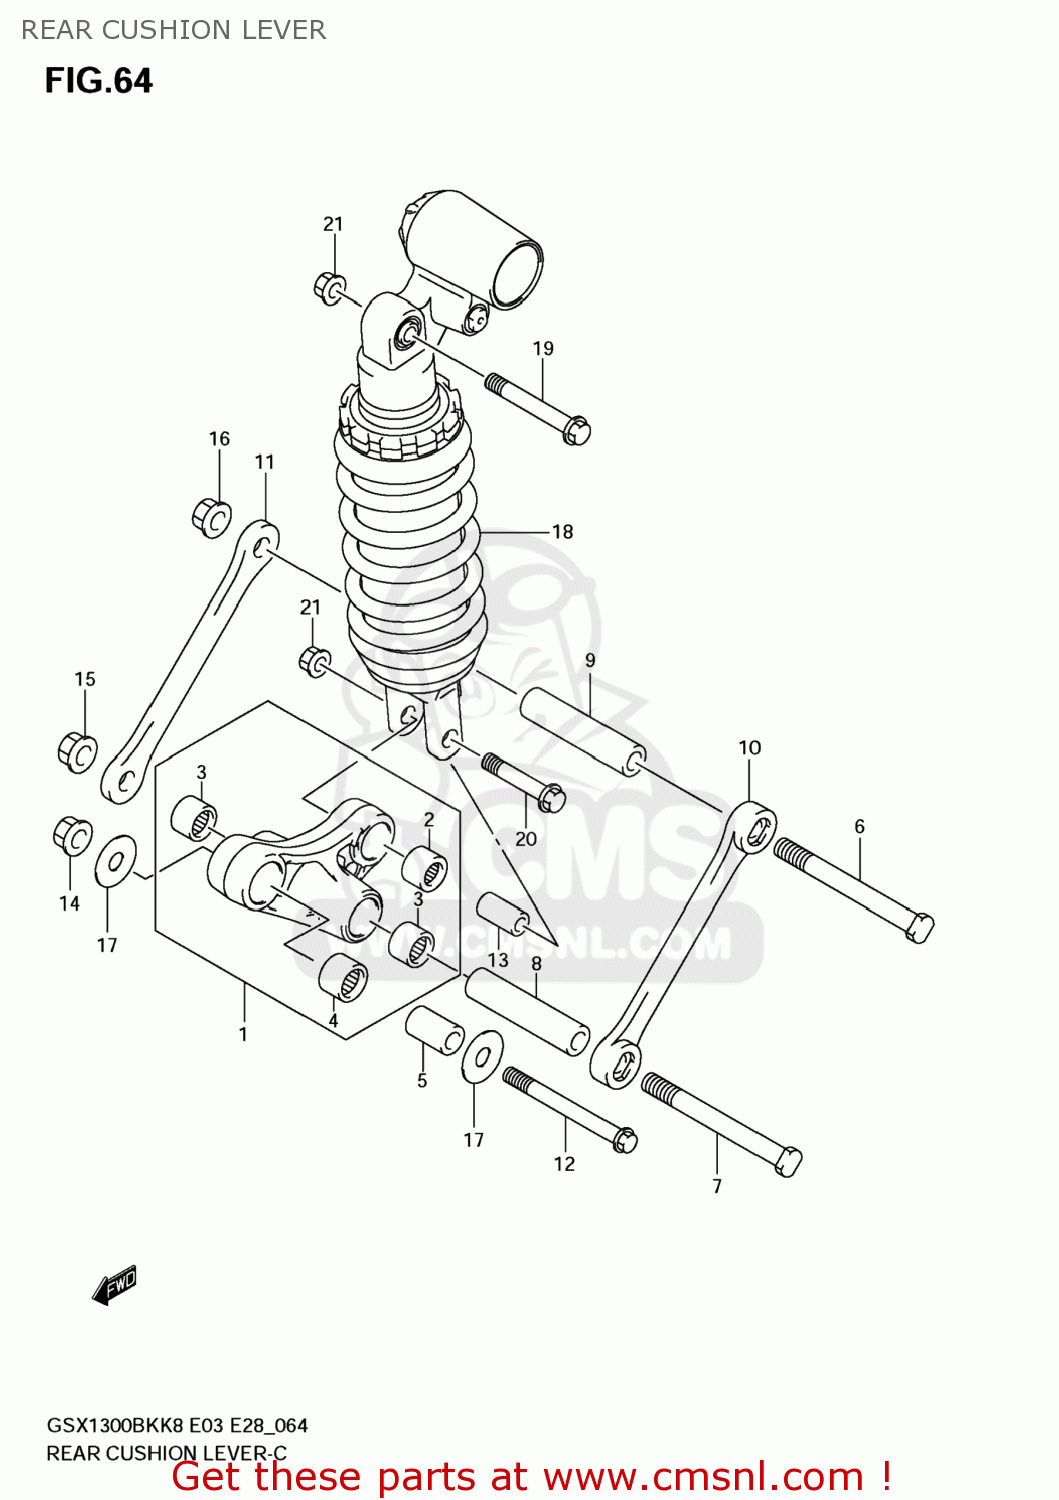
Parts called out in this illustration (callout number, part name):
1	LEVER SET,RR CUSHION
2	BEARING(17X24X26)
3	BEARING(17X24X25)
4	BEARING(20X27X32)
5	SPACER,RR CUSHION LEVER FR
6	BOLT,RR CUSHION LEVER CTR
7	BOLT,RR CUSHION LEVER CTR
8	SPACER,RR CUSHION LEVER CTR
9	SPACER,RR CUSHION LEVER CTR
10	ROD,RR CUSHION,L
11	ROD,RR CUSHION,R
12	BOLT,RR CUSHION LEVER FR
13	SPACER,RR CUSHION LEVER
14	NUT
15	NUT
16	NUT
17	WASHER(12X34X1)
18	ABSORBER ASSY,RR SHOCK
19	BOLT(10X70)
20	BOLT(10X55)
21	NUT
